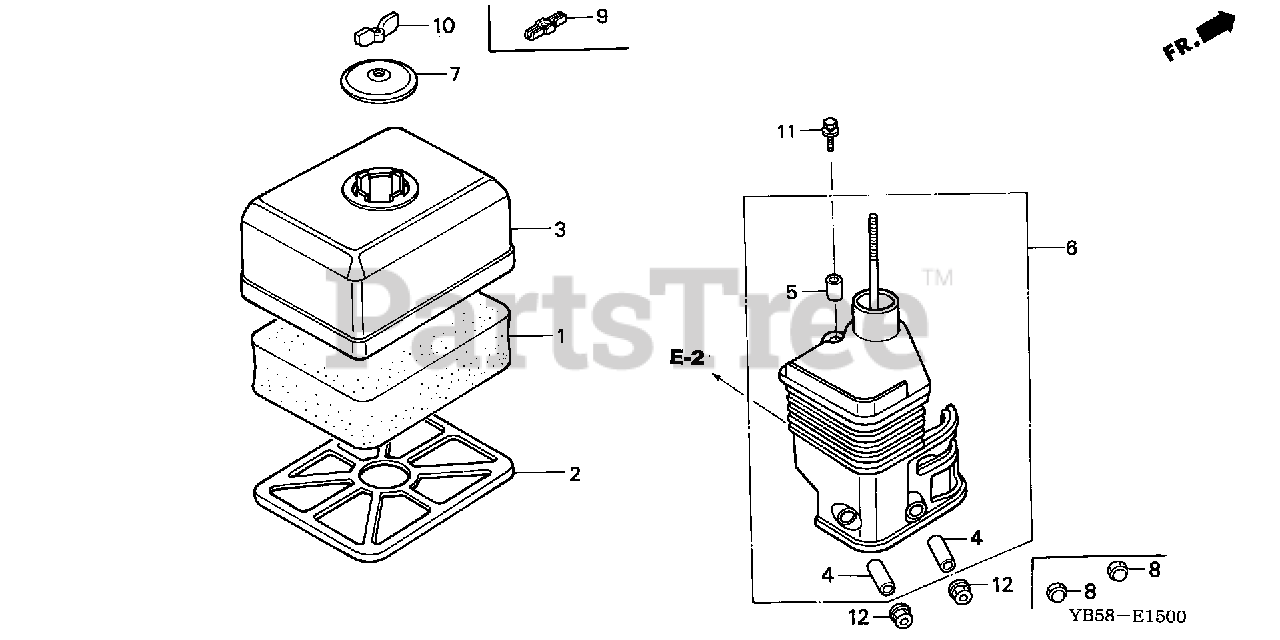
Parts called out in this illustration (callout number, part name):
1	ELEMENT, AIR CLEANER (SEMI-DRY)
2	GRID, AIR CLEANER (SEMI-DRY)
3	COVER, AIR CLEANER (SEMI-DRY)
4	COLLAR, AIR CLEANER
5	COLLAR B, AIR CLEANER
6	ELBOW, AIR CLEANER
7	CAP, CLEANER
10	NUT, TOOL BOX SETTING
11	BOLT, FLANGE (6X20)
12	NUT, FLANGE (6MM)
